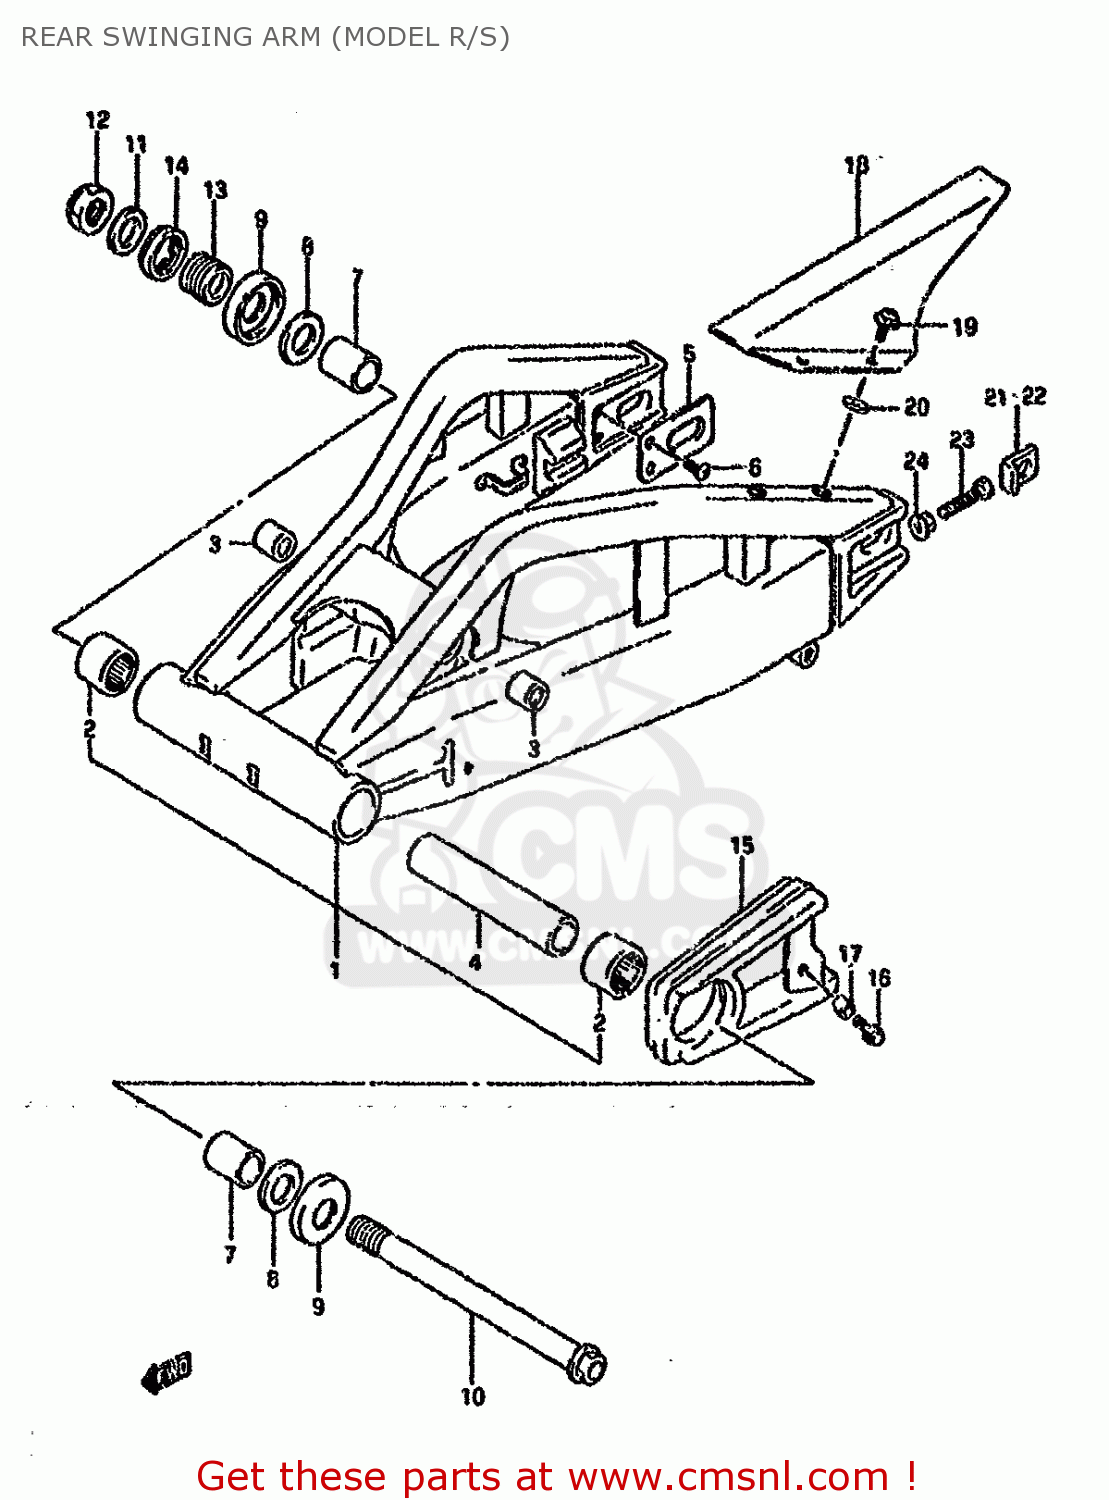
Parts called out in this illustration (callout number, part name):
1	SWING ARM ASSEMBLY,REAR
2	BEARING(30X40X25)
3	BEARING(17X24X20)
4	SPACER (25.4X31.8X157.9)
5	PLATE,RR SWING ARM BRKT
6	SCREW 6X10
7	SPACER,REAR SWING ARM PIVOT
8	WASHER
9	DUST SEAL,RR SWGARM PIVOT
10	SHAFT,REAR SWING ARM PIVOT
11	WASHER(25.2X42X3.2)
12	NUT
13	BOLT,REAR SWING ARM PIVOT
14	NUT,REAR SWING ARM PIVOT BOLT
15	BUFFER,CHAIN TOUCH DEFENSE
16	BOLT 6X20,WITH PLAIN WASHER
17	SPACER
18	CASE,CHAIN
19	SCREW(6X20)
20	WASHER
21	WASHER,CHAIN ADJUSTER
22	WASHER,CHAIN ADJUSTER
23	BOLT(8X50)
24	NUT
